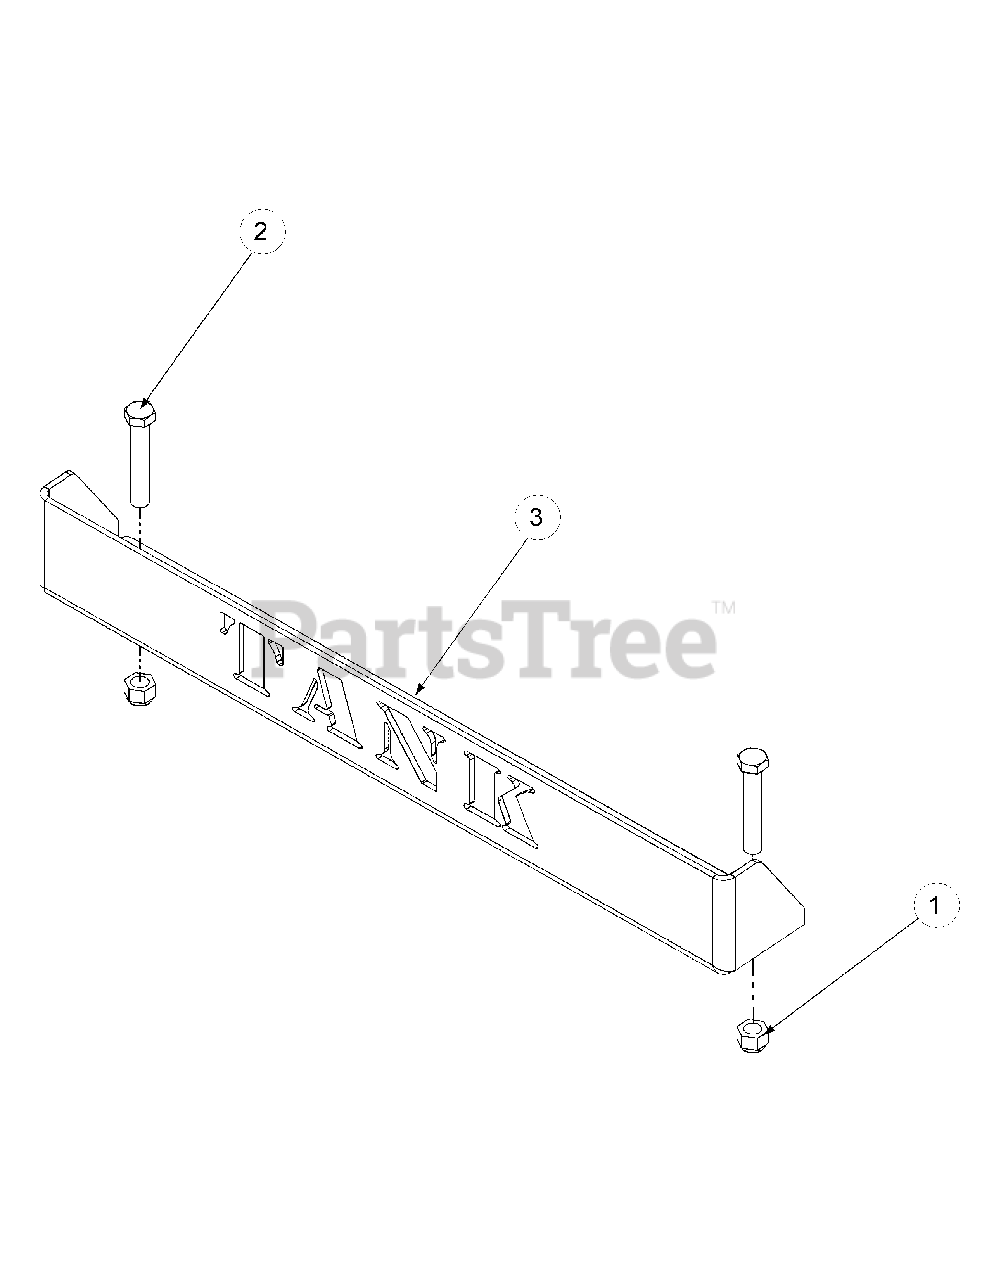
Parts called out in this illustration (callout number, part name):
1	Hex Nut, 1/2-13, Insert Lock
2	HHCS, 1/2-13, 3.00
3	Rear Bumper Plate
